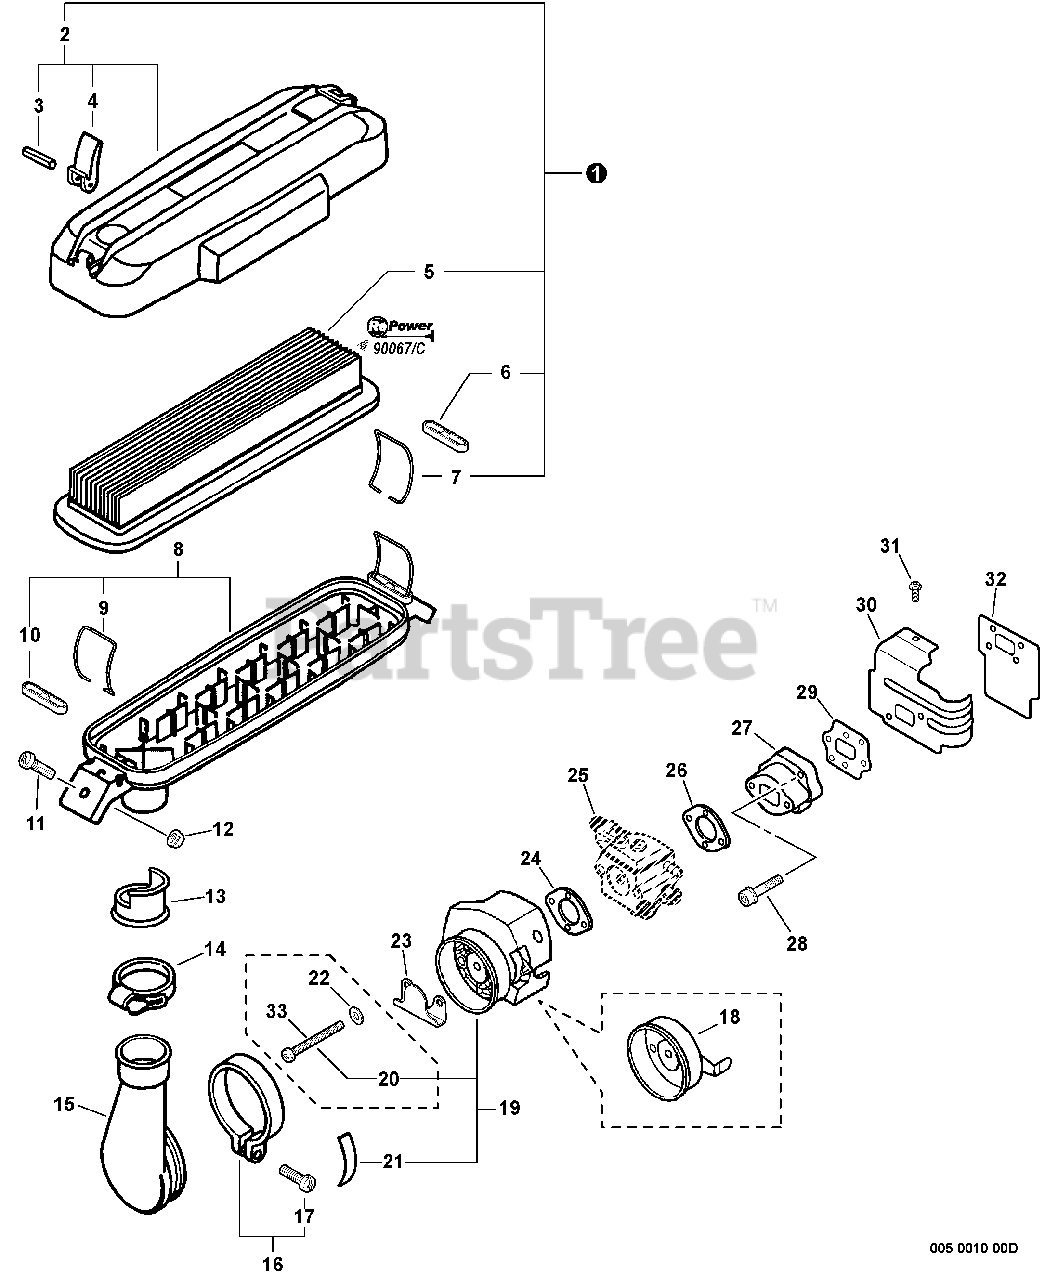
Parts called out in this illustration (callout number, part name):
1	AIR FILTER KIT
2	AIR FILTER COVER ASSY
3	PIN - SPRING -- 3X25
5	FILTER, AIR
6	RETAINER
7	RING, RETAINING
8	AIR FILTER CASE ASSY
9	RING, RETAINING
10	RETAINER
11	SCREW - 5X14
12	NUT - 5 -- FLANGE
14	CLAMP, HOSE
15	ADAPTOR, INTAKE
16	CLAMP KIT
17	SCREW - 5X25
18	BRACKET, AIR CLEANER - METAL
19	BRACKET KIT - PLASTIC
20	SCREW - 5X57
21	LABEL - CHOKE
22	WASHER - 6
23	PLATE, PREVENT
24	GASKET, INTAKE
25	CARBURETOR
26	GASKET, INTAKE
27	INSULATOR, INTAKE
28	SCREW - 5X25
29	GASKET, INTAKE
30	COVER, CYLINDER - INTAKE
31	SCREW - 5X10
32	SHIELD, INTAKE
33	SCREW - 5X55
34	RePower TUNE-UP KIT
